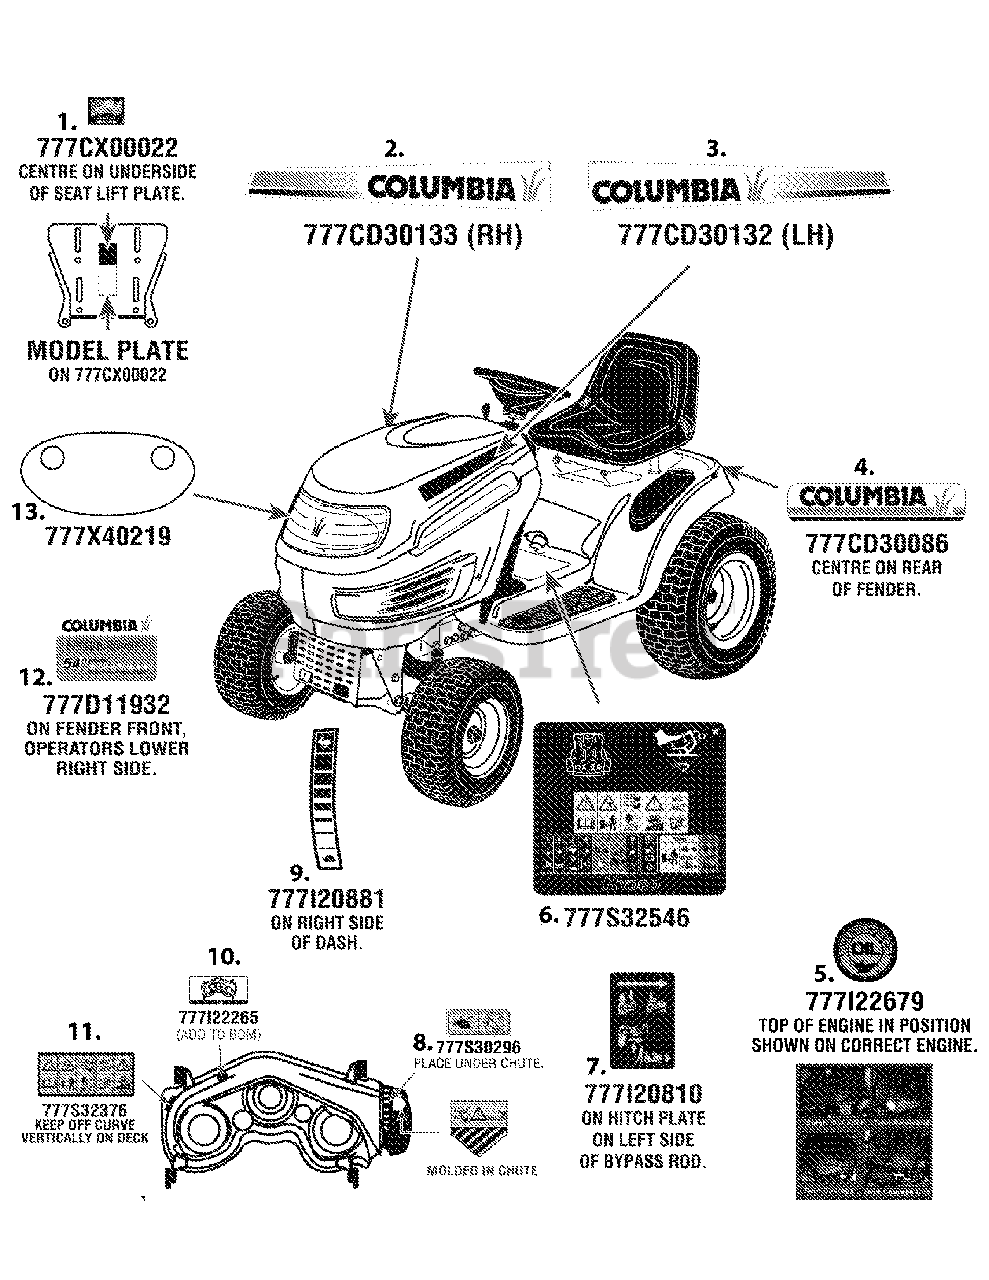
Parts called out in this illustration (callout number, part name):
1	LBLX: MADE IN USA
2	LABEL-HOODSIDE RH STY 6 COLUMBIA
3	LABEL-HOODSIDE LH STY 6 COLIMBIA
4	LABEL-REAR FENDER COLUMBIA
5	LABEL-SAFETY/INST CANADA
6	LABEL-CHECK ENG OIL
7	LABEL-HITCH PLATE BYPASS ROD
8	LABEL:RIDER DECK: UNDERCHUTE EXP
10	LABEL-BELT ROUTE
11	LABEL:RIDER:SAFETY DECK
12	LABEL-HYD 54" FNDR COLUMBIA
12	LABEL-RDR:FNDR:46:HYDRO:GT:597
13	LABEL-LENS REFLECT
